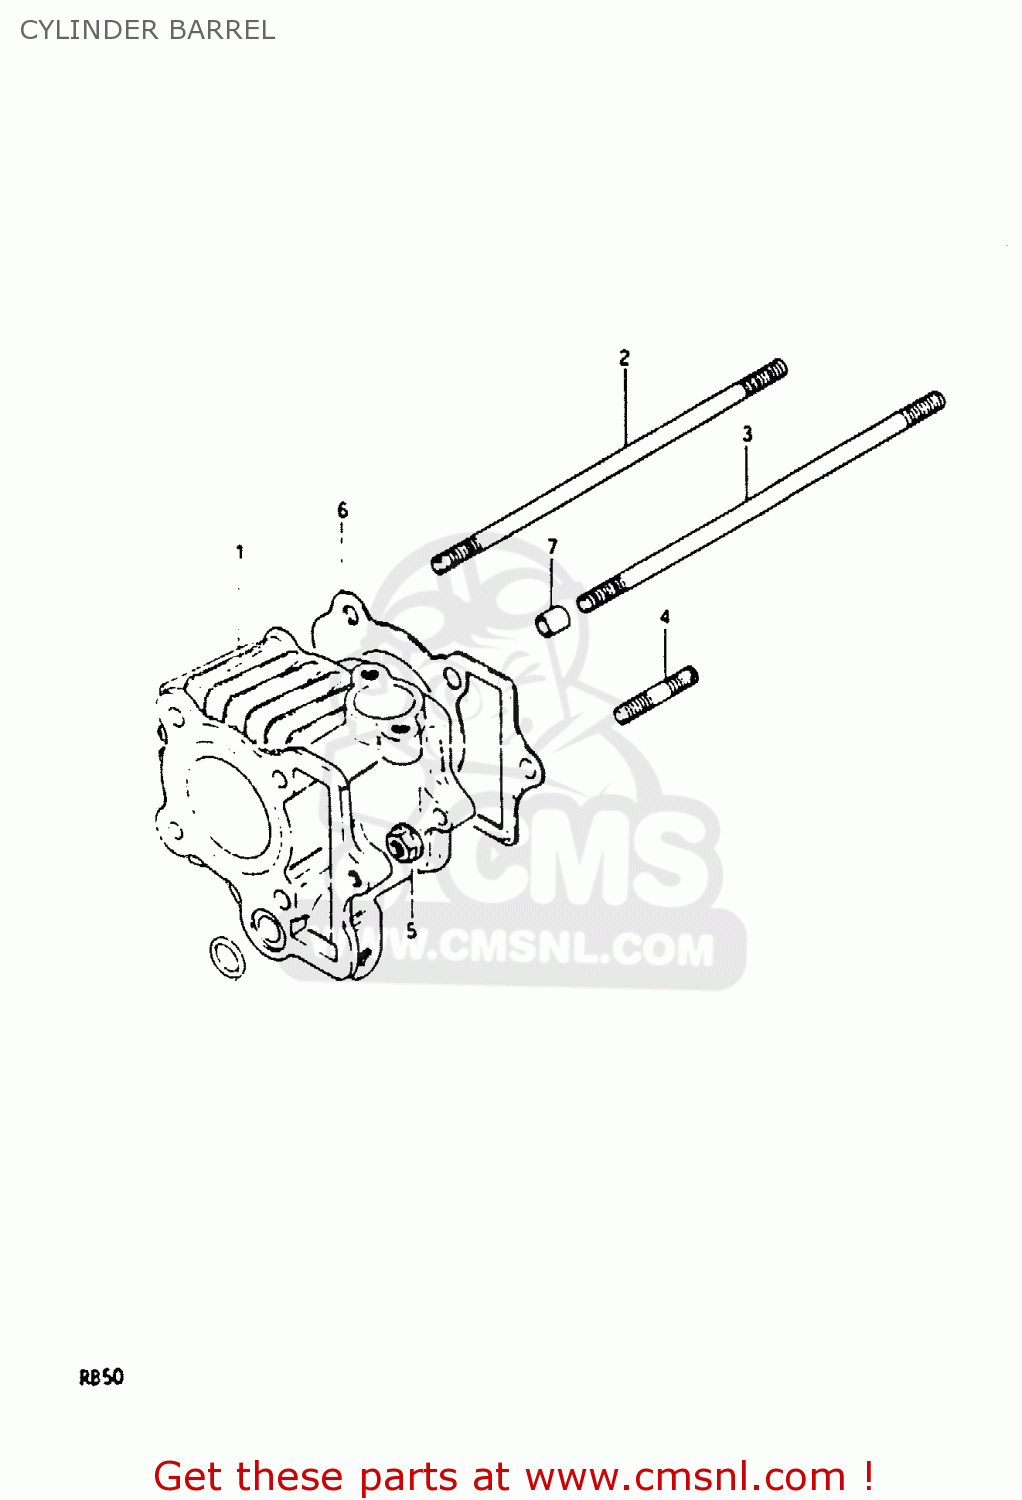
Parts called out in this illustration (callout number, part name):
1	CYLINDER
2	BOLT,STUD
3	BOLT,STUD
4	STUD 6X20
5	NUT
6	GASKET,CYLINDER
7	PIN(6.2X8X11)
8	O-RING
